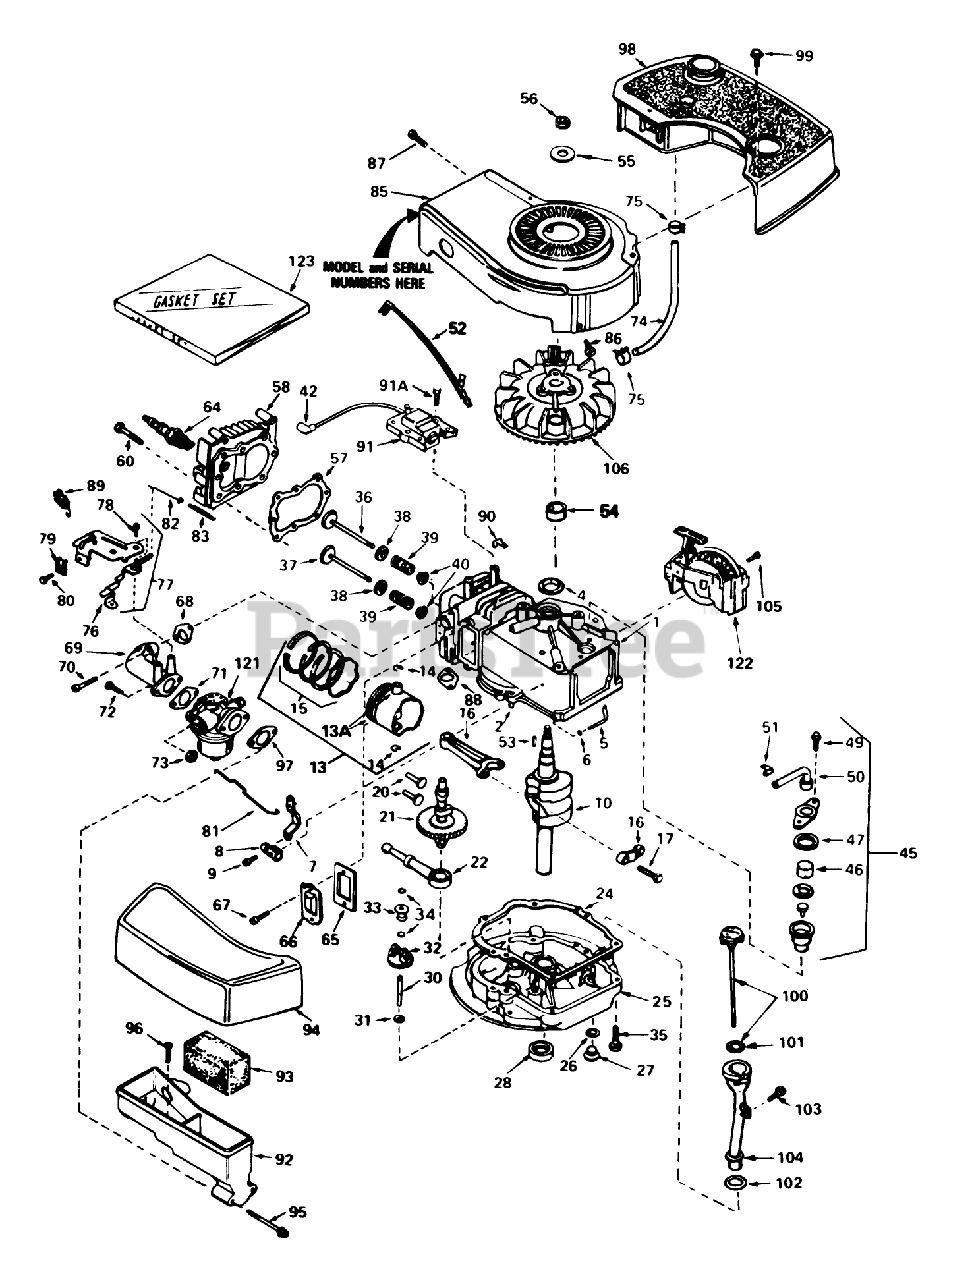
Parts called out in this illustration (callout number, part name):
1	Cyiinder Assy. (Incl. Ref. #2, 4 105)
2	Pin-Dowel
4	Seal-Oil
5	Rod, Governor (Incl. No. 36)
6	Washer-Flat
7	Governor Lever
8	Clamp-Lever, Governor
9	Screw
10	Crankshaft
13	Piston, Pin Ring Assy. (Std.) (Incl. Ref. #13A, 14 15)
13	Piston, Pin Ring Assy. (.010 oversize) (Incl. Ref. #13A, 14 15)
13	Piston, Pin Ring Assy. (.020 oversize) (Incl. Ref. #13A, 14 15)
13A	Piston Pin Assy. (Incl . Ref. . #14) (Std.)
13A	Piston Pin Assy. (Incl. Ref. #14) (.010 Oversize)
13A	Piston Pin Assy. (.020 oversize) (Incl. Ref. #14)
14	Ring-Retaining, Piston Pin
15	Ring Set (Std.)
15	Ring Set (.020" OS)
15	Ring Set (.010" OS)
16	Rod Assy., Connecting (Incl. Ref. #17)
17	Bolt-Rod, Connecting
20	Lifter-Valve
21	Camshaft(Mech.Comp. Release)
22	Oil Pump ASM
24	Gasket, Mounting
25	Flange Assy., Mounting (Incl. Ref. #26thru 30)
26	Gasket-Oil Drain
27	Plug Oil Drain
28	Seal Oil
30	Shaft-Governor
31	Washer-Flat
32	Governor Gear ASM
33	Spool-Governor
34	Ring-Retaining
35	Screw (1/4-20 x 1-1/4)
36	Valve, Intake (Std.) (Incl. Ref. #40)
36	Valve, Intake (1/32" oversize)(Incl. No. 40)
37	Valve, Exhaust (Std.)(Incl. No. 40)
37	Valve, Intake (1/32" oversize)(Incl. No. 40)
38	Cap-Upper Valve Spring
39	Spring-Valve
40	Cap-Valve, Spring
42	Cover-Spark Plug
45	Breather Assy. (Incl. Ref. #46 thru 51)
46	Element-Breather
47	Gasket-Breather
49	Screw (10-24 x 9/16)
50	Tube, Breaker
51	Clip, Breather
52	Wire-Ground
53	Key-Flywheel
54	Spacer
55	Washer-Belleville
56	Nut-Flywheel
57	63573 GIL 42 SNWTHW
58	Head-Cylinder
60	Screw (5/16-18x1-1/2)
64	Plug, Spark (J17LM or equiv.)
64	Plug, Spark (Champion RCJ-8)
65	Gasket-Breather
66	Cover-Valve
67	Screw
68	Gasket-Intake
69	Pipe, Intake (Incl. No. 68)
70	Screw (1/4-20 x 1)
71	Gasket-Carburetor
73	Nut and Lock Washer (1/4-28)
74	Line-Fuel
75	Clamp-Line, Fuel
76	Lever Control
77	Control Assy., Speed (Incl. Nos, 76, 78 89)
78	Screw, Hex Washer Hd Shoulder Self-Tap
79	Conduit
80	Screw (10-32 x 3/8)
81	Link-Throttle
82	Link Governor Spring
83	Spring Governor
85	Housing-Blower
86	Screw (1/4-20x19/32)
87	Screw (10-24 x 9/16)
88	Gasket Exhaust
89	Terminal
90	Clip-Wire
91	Solid State
91A	Screw
92	Body Air Cleaner
93	Filer, Air
94	Cove, Air Cleaner
95	Screw Fil Hd.
96	Screw, Hex Hd.
97	Gasket-Air Cleaner
98	Tank-Fuel
99	Screw (10-32 x 35/64)
100	Dipstick, Oil (Incl. Ref. #101)(Twist Lock)
101	O-Ring
102	Gasket
103	Screw (10-32 x 1/2)
104	Tube-Oil Fill
105	Screw (1/2-20x5/8)
106	Flywheel
121	Carburetor (Incl. Ref. #71)
122	Starter-Sidemount
123	Gasket Set
